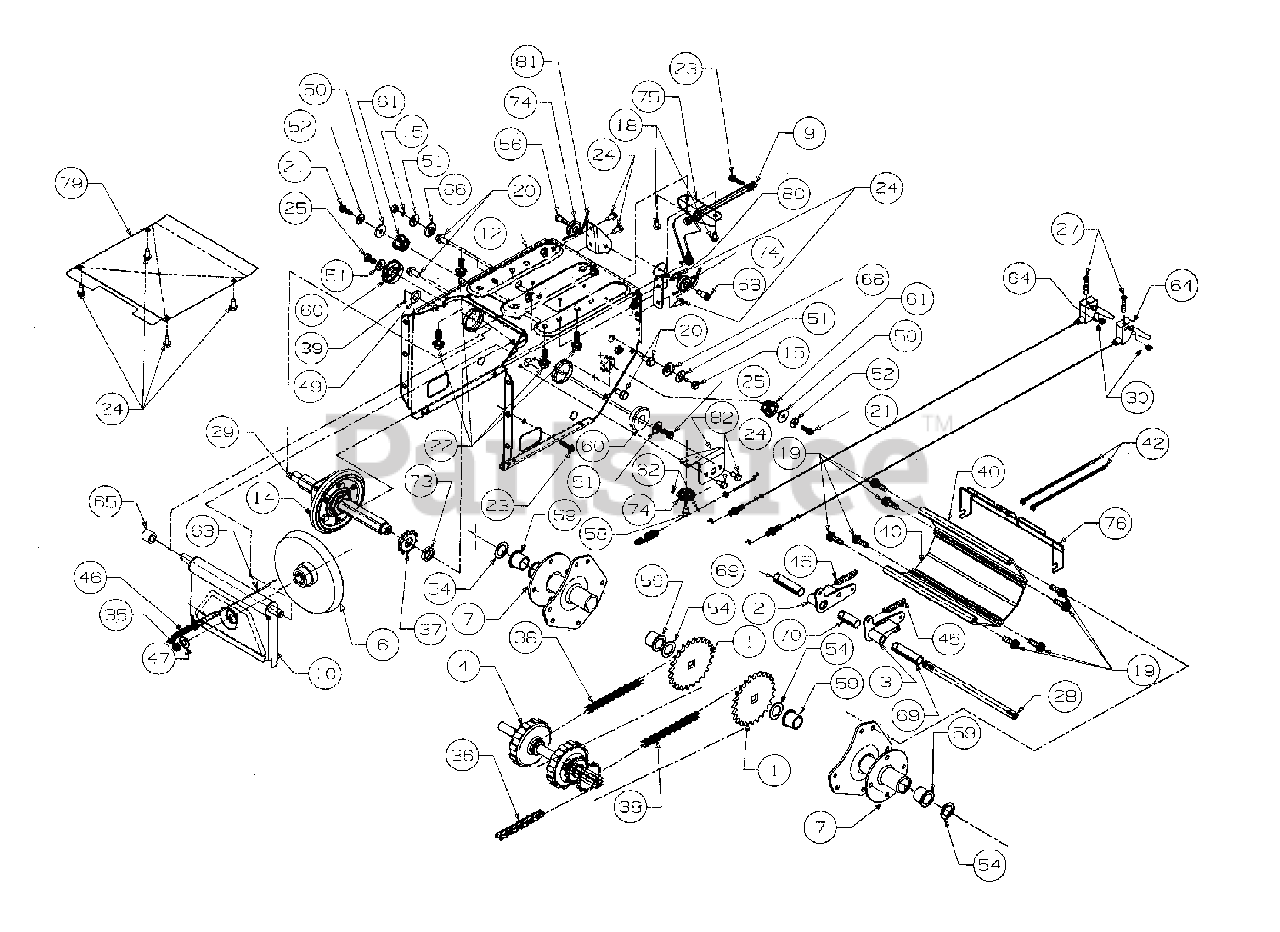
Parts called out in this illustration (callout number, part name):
1	Axle Assembly
2	Dog Assembly - R.H.
3	Dog Assembly - L.H.
4	Shaft Assembly
6	Disc Assembly
14	Wheel Assembly Friction
15	Screw
18	Screw
19	Screw
20	Screw
21	Screw
23	Screw
24	Screw
25	Screw
27	Screw
28	Shaft
29	Shaft
30	Nut Flange
35	Nut Jam
36	Chain
37	Sprocket
38	Chain
39	Pin Cotter
40	Housing Track
42	Cable Tie
45	Spring
46	Spring
47	Washer - Bell
49	Washer - Flat
50	Washer - Flat
51	Washer - Bell
52	Washer - Bell
54	Washer - Flat
56	Lubricant
58	Screw - Shoulder
59	Bearing - Flange
60	Bearing - Ball
61	Bearing - Hex Flange
62	Cable - Auger Clutch
63	Cable - Drive Clutch
64	Cable with Trigger Lever
65	Spacer
66	Spacer - Shoulder
69	Spacer - Split
70	Spacer - Split
73	Spacer
74	Roller - Cable
